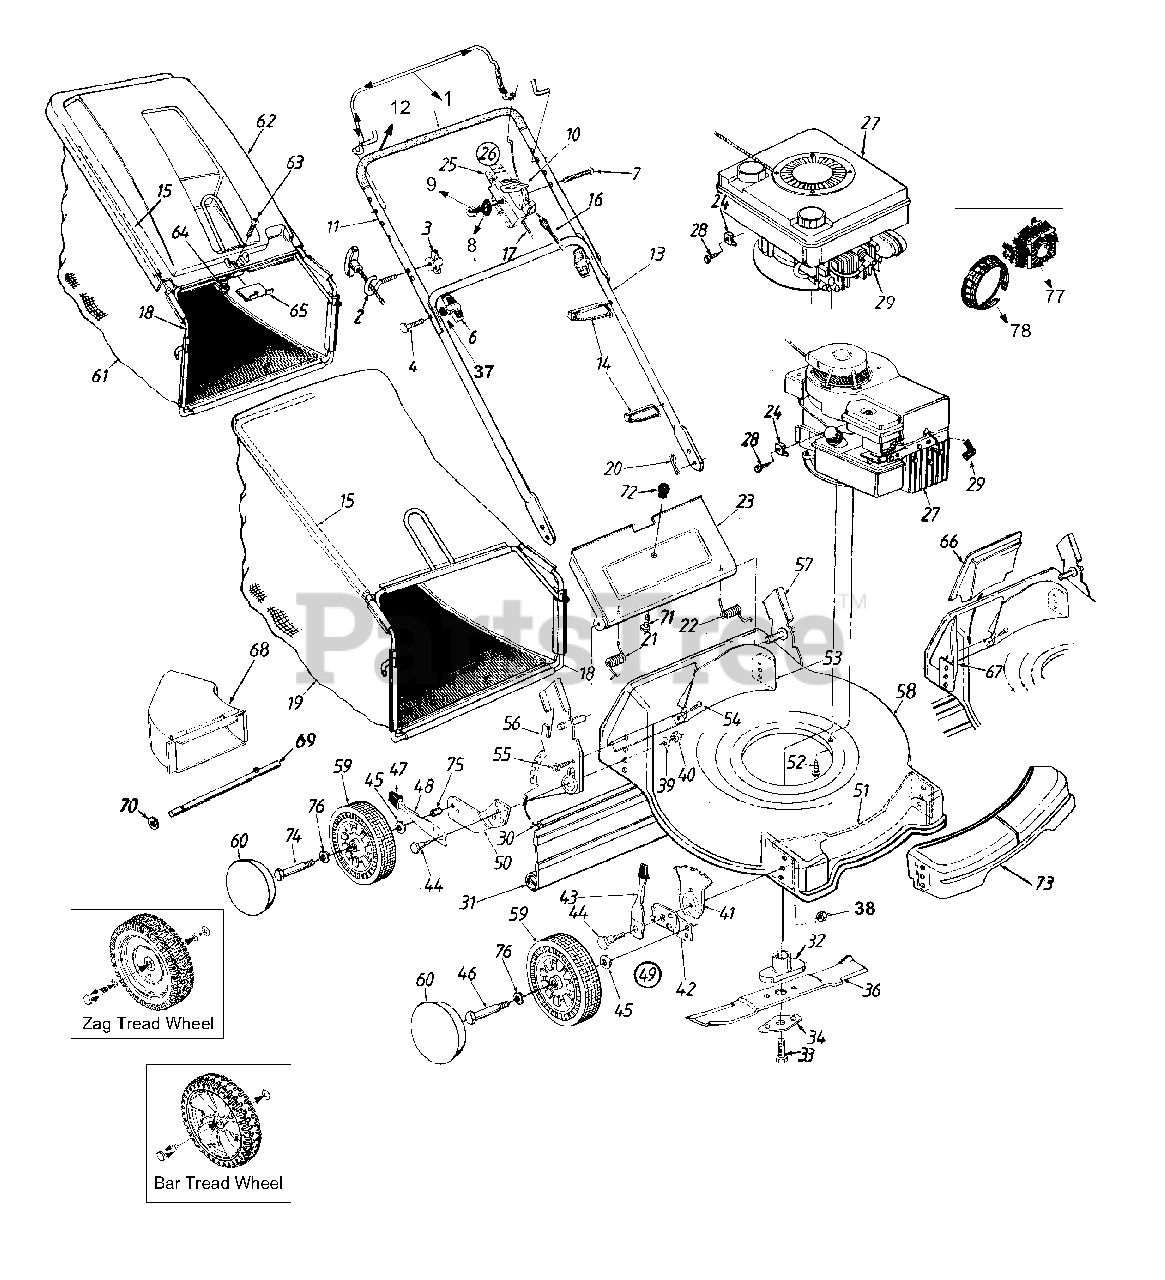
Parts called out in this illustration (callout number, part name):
2	Rope Guide
3	Handle Knob 1/4-20 Thd.
4	Curved Hd. Bolt 5/16-18 x 2" Lg
6	Hand Knob
7	Oval C-Sunk Mach. Scr.
8	Spring Washer .66" I.D.
9	Hex L-Nut 1/4-20 Thd.
10	Throttle Lever
14	Cable Tie
16	Control Cable- 37.25"
17	Throttle Control Wire - 42"
20	Int. Cotter Pin 5/16" Dia.
21	Door Spring - R.H.
22	Door Spring - L.H.
25	Throttle Body
26	Throttle Box Comp. (Models with Honda engine only)
27	Engine
28	Hex Wash. Hd. Scr. #10-32 x .62" Lg. (B&S)
29	Spark Plug Boot
30	Wire Rod
31	Rear Flap
32	Blade Adapter Kit
33	Hex Bolt 3/8-24 x 1.5" Lg.
34	Blade Bell Support
36	21" Mulching Blade
37	Saddle Wash. .320 I.D. x .93 O.D.
38	Flange L-Nut 3/8-16 Thd.
39	Bell-Wash. .39" I.D. x 1.38"
40	Hex Nut 3/8-16 Thd.
41	Height Adj. Plate
43	Spring Lever Ass'y. w/Knob
44	Shld. Bolt .5" Dia. x .357"
45	Bell-Wash. .38" I.D. x .88" O.D.
46	Axle Bolt
47	Spring Lever Knob
48	Spring Lever
49	Height Adj. Assembly Comp. - R.H.
50	Pivot Bar R.H.
54	Torx Mach. AB-Tap Scr. 1/4 x 62"
55	Wash.Scr. 1/4 -14 x .625
56	Handle Bracket Assembly - R.H.
57	Handle Bracket Assembly - L.H.
60	Hub Cap - Gray , Rad. Spoke
61	Grass Bag
62	Hard Top Cover w/o Logo
63	Pan Hd. Mach. Scr. 1/4-20 x .5" Lg.
64	Hex Nylon L-Nut 1/4-20 Thd.
66	Mulching Baffle Plug
68	Deflector
69	Rod
70	Push Speed Nut
71	Truss Scr. #10-24 x .38" Lg.
73	Deck: Front Cover
74	Rear Axle Bolt
75	Spacer
76	Wave Washer
